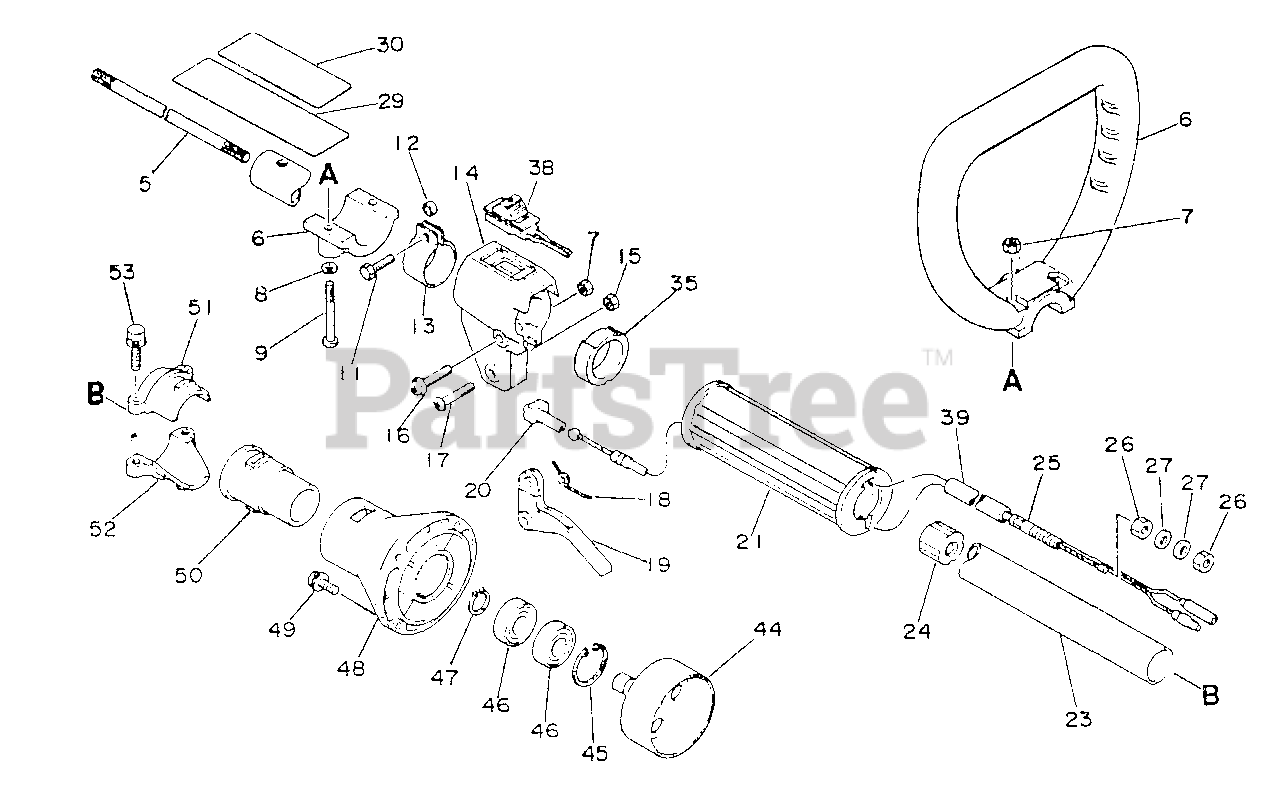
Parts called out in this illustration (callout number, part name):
5	DRIVESHAFT
6	LOOP HANDLE ASSY
7	NUT M5
8	WASHER, FLAT 5.5×10×0.8
9	SCREW 5×40
11	BOLT 5×18
12	SPACER, GUARD
14	BRACKET, THROTTLE CONTROL
15	LOCKNUT - 5
16	SCREW 5×30
18	SPRING, THROTTLE
19	TRIGGER, THROTTLE
20	GUIDE, CABLE
23	MAIN PIPE ASSY 25×L= 1500
24	STOPPER
25	CABLE, THROTTLE
27	WASHER 6.5×11.5×0.8
29	LABEL - CAUTION
38	IGNITION SWITCH ASSY
44	DRUM, CLUTCH
45	RING, SNAP 28
46	BEARING, BALL 6001
47	RING, RETAINING - 12
48	CASE, CLUTCH - ORANGE
49	SCREW 5×16
51	HOLDER, MAIN PIPE - UPPER
53	BOLT - 5×25
